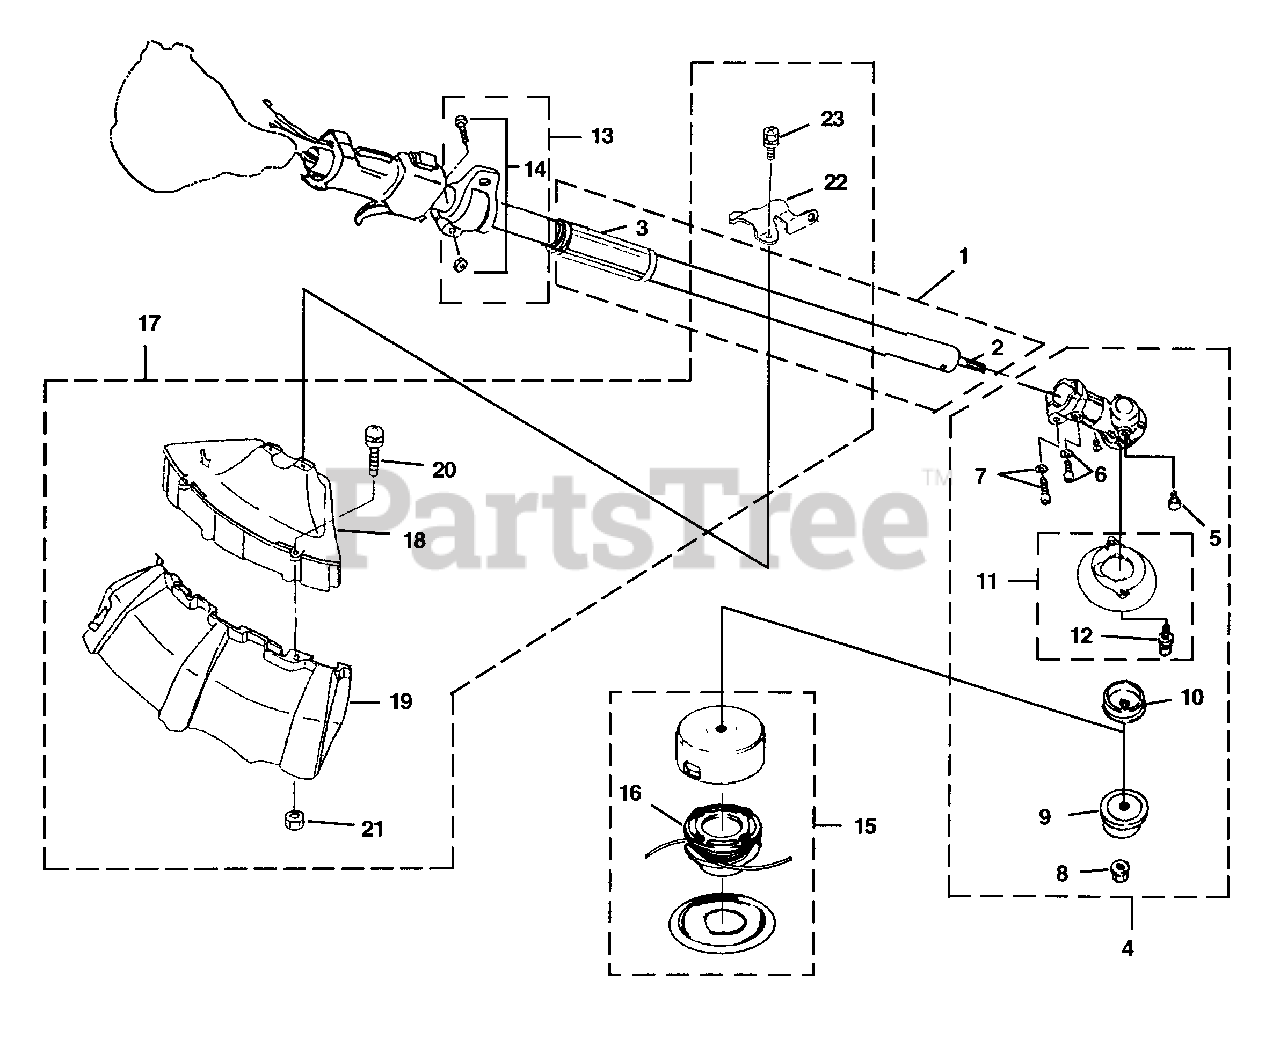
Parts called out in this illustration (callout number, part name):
1	DRIVESHAFT HOUSING
2	DRIVESHAFT
4	GEAR HEAD
5	BOLT-Grease
6	BOLT ASSEMBLY
7	BOLT ASSEMBLY (M5 X 25 SW)
8	NUT
9	WASHER-Cupped
10	WASHER-Flange
11	GRASS GUARD
12	SCREW-Socket Hd (M5 x 12 W SW)
13	HANGER ASSEMBLY
14	SCREW ASSEMBLY
15	STRINGHEAD ASSEMBLY (.095)
16	SPOOL & STRING (.095)
17	PROTECTOR ASSEMBLY
18	PROTECTOR COMPLETE
19	PROTECTOR COMPLETE
20	SCREW ASSEMBLY
22	CLAMP-Protector
23	BOLT ASSEMBLY
